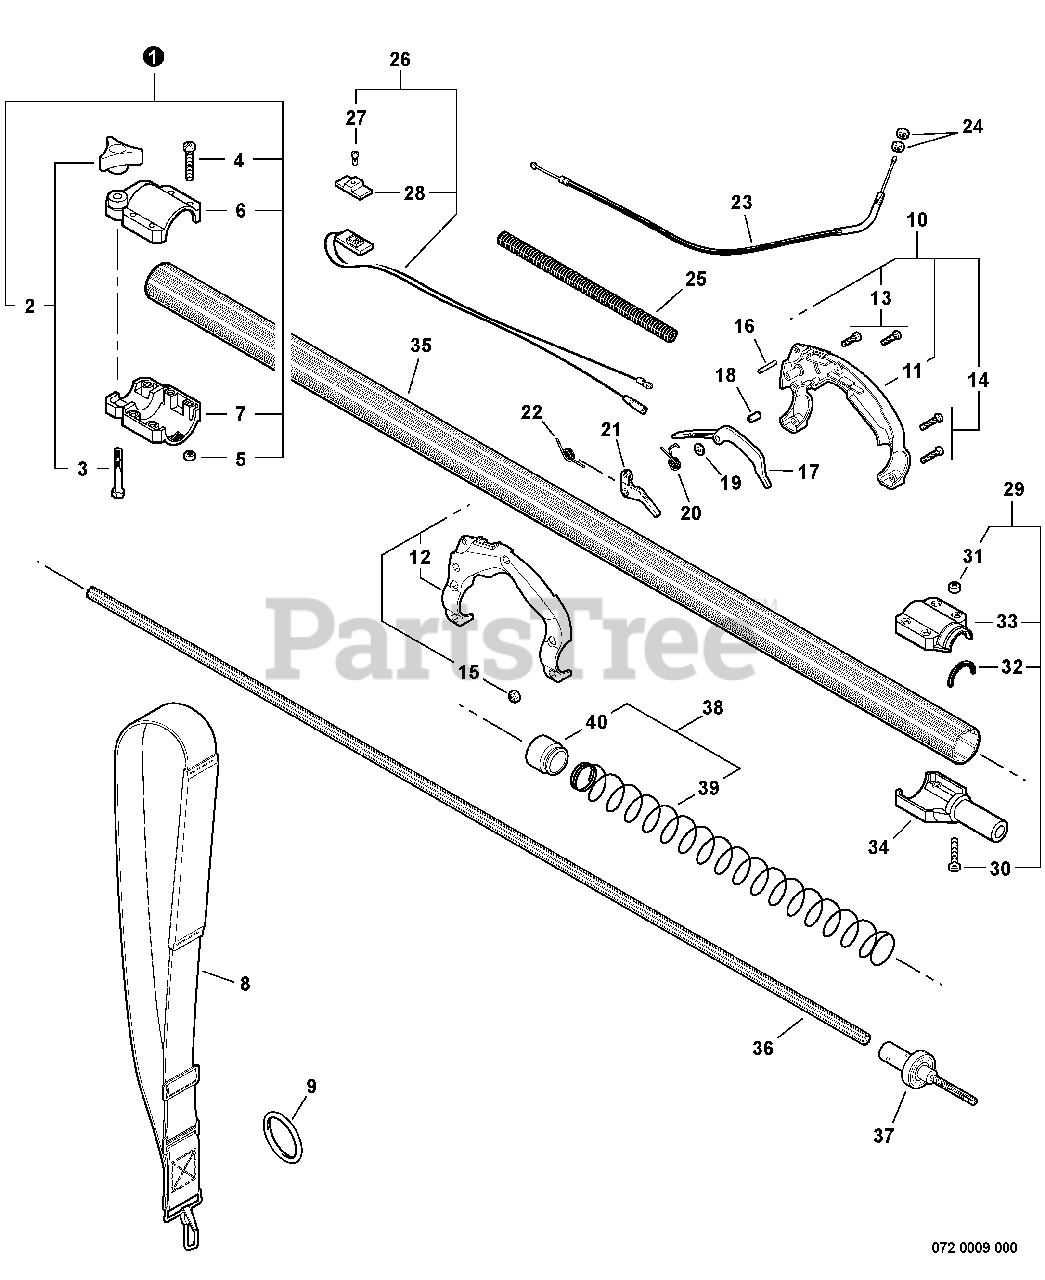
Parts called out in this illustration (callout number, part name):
1	CLAMP ASSY
2	THUMBSCREW
4	SCREW, TORX 10-24 UNC 1-1/4
5	NUT, LOCK 10-24 UNC
6	COLLAR, UPPER
7	COLLAR, LOWER
8	STRAP ASSY, SHOULDER
9	RING, HARNESS Ø32
10	HANDLE SET, REAR
11	HANDLE, LEFT REAR
12	HANDLE, RIGHT REAR
13	SCREW, TORX 10-24 UNC 1-1/4
14	SCREW, TORX 10-24×1.5
15	NUT, LOCK 10-24 UNC
16	PIN, LOCATING 0.17 OD×0.75 L
17	LOCKOUT, THROTTLE
18	COLLAR 5.08×14.5
19	WASHER 5.5×12×0.8
20	SPRING, TORSION Ø0.39 I.D.
21	TRIGGER, THROTTLE
22	SPRING, TORSION
23	CABLE, THROTTLE
25	TUBE, FLEXIBLE
26	SWITCH, ON-OFF
27	SCREW 3×10
28	KNOB, SWITCH - ORANGE
29	CAP ASSY, MAIN PIPE
30	SCREW, TORX 10-24×1.5
31	NUT, LOCK 10-24 UNC
33	CAP, MAIN PIPE
34	COUPLING, MAIN PIPE 113.6 L
35	PIPE, MAIN 1.5 ID×60" L
36	DRIVESHAFT
37	SHAFT, LOWER DRIVE
38	BUSHING ASSY, FLOATING
39	SPRING, COMPRESSION
40	BUSHING, FLOATING
